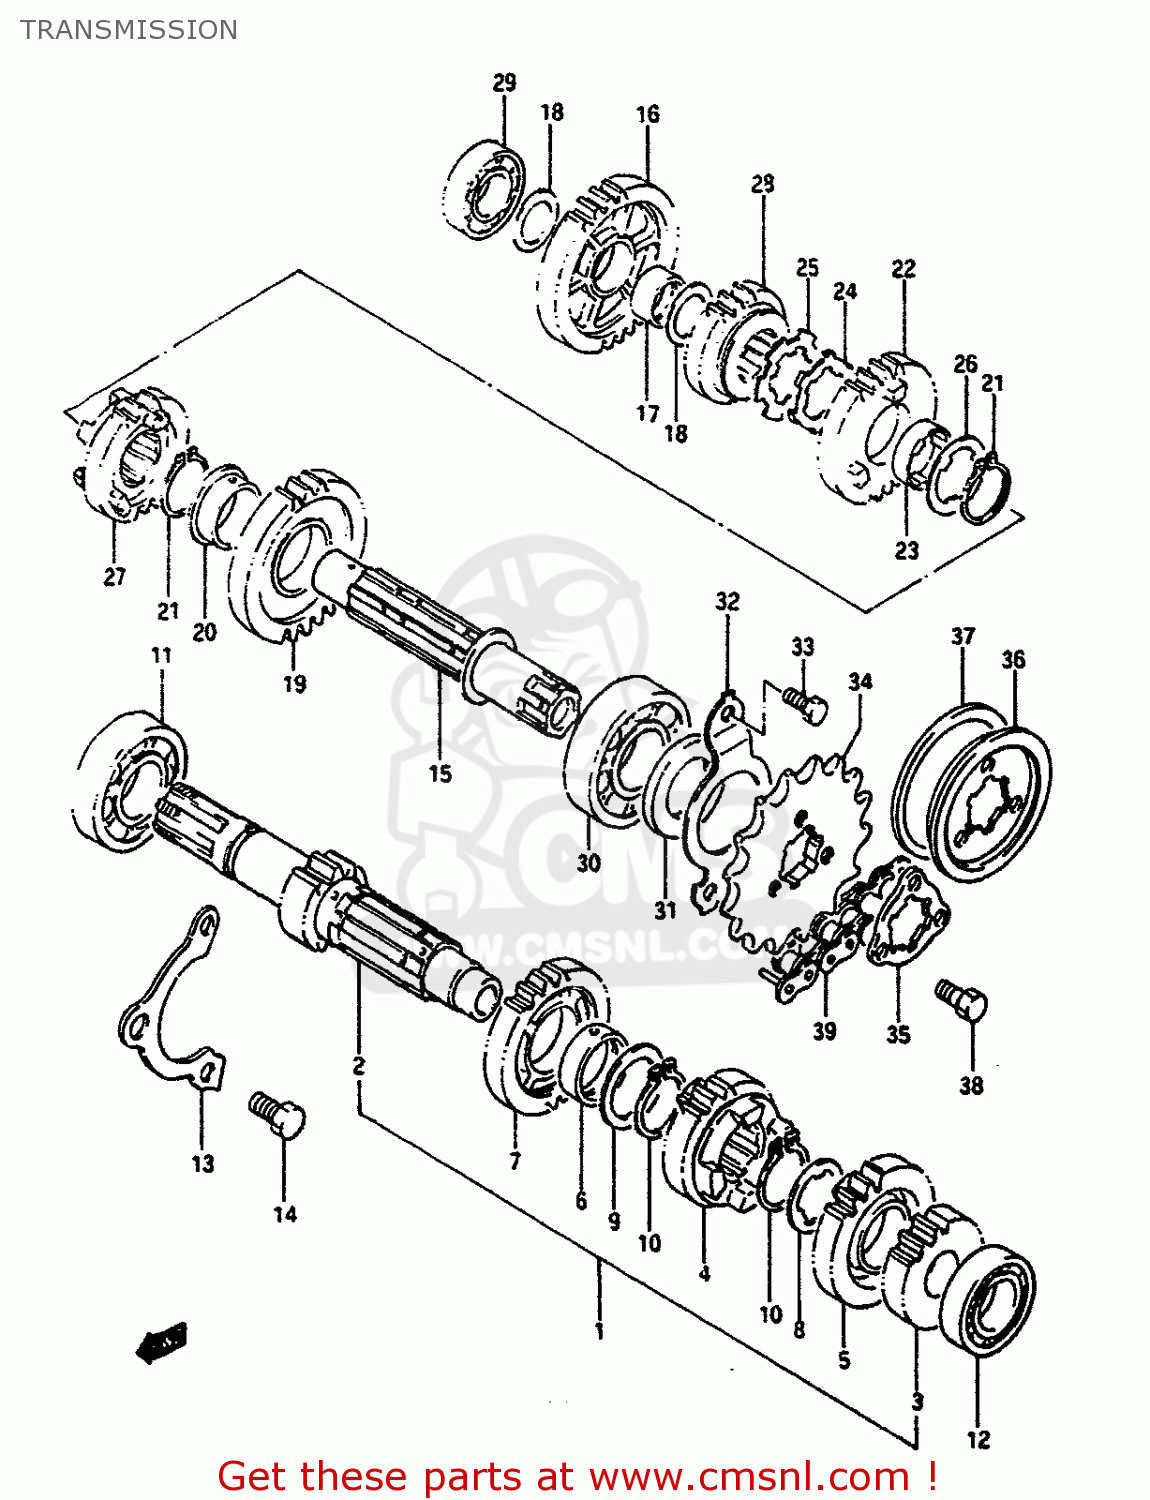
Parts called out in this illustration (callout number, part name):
1	SHAFT,COUNTER
2	SHAFT,COUNTER
3	GEAR,SECOND DRIVE
4	GEAR,THIRD DRIVE
5	GEAR,FOURTH DRIVE
6	BUSHING 25X29X10
7	GEAR,5TH DRIVE
8	WASHER,LOCK
9	WASHER
10	RING,SNAP
11	BEARING
12	BEARING
13	RETAINER,CNTR SHAFT BEARING
14	BOLT, 8X1.25X1
15	SHAFT,DRIVE
16	GEAR,1ST DRIVEN
17	BUSH(20X24X13)
18	WASHER
19	GEAR,2ND DRIVEN
20	BUSH
21	RING,SNAP
22	GEAR,THIRD DRIVEN
23	BUSHING
24	WASHER
25	WASHER,LOCK
26	WASHER,LOCK
27	GEAR,FOURTH DRIVEN
28	GEAR,FIFTH DRIVEN
29	BEARING(20X42X12)
30	BEARING(25X62X17)
31	SEAL,OIL(25X45X5)
32	RETAINER,DRIVESHAFT O
33	BOLT
34	SPROCKET,ENGINE(NT:16)
35	PLATE,ENGINE SPROCKET
36	PLATE,ENGINE SPROCKET
37	DAMPER,ENGIN SPROCKET
38	BOLT
39	CHAIN ASSEMBLY,DRIVE
